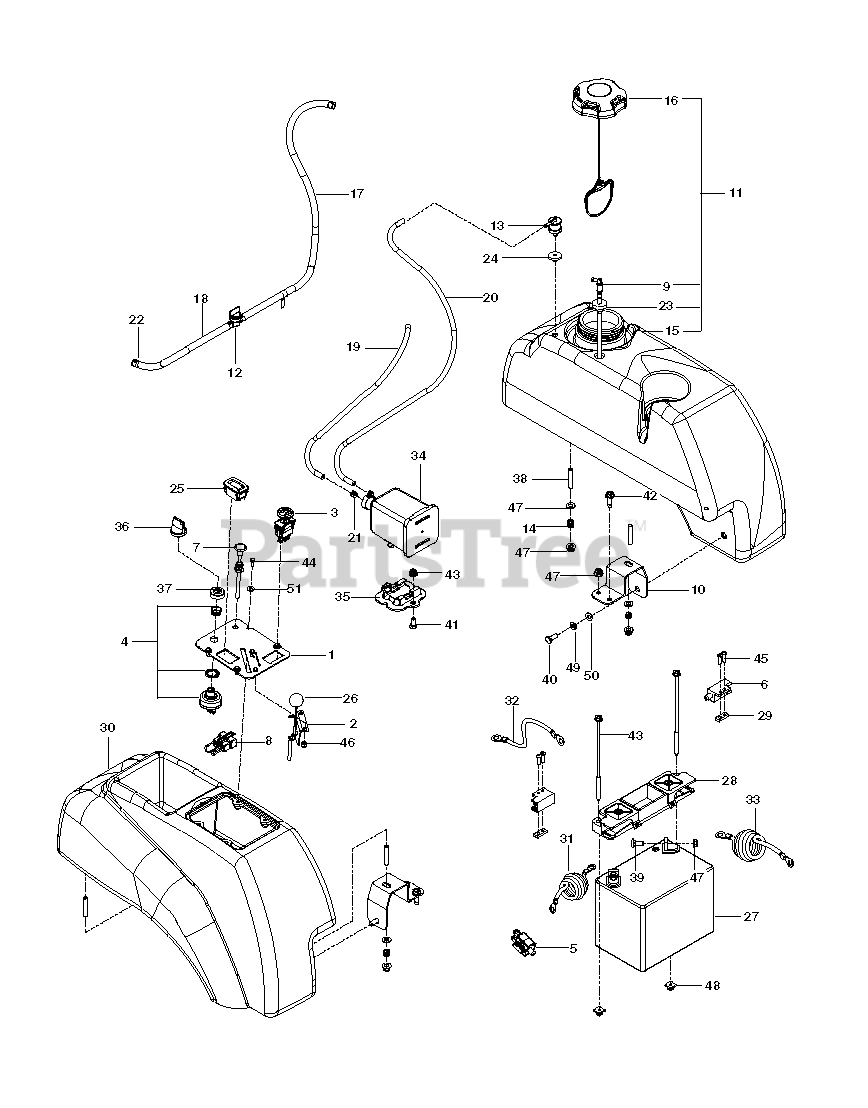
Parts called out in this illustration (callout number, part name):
1	PLATE.CONSOLE.BLACK
2	THROTTLE CABLE
3	SWITCH, PTO 10 AMP
4	SWITCH, IGNITION, INDAK
5	SWITCH, BRAKE 3P
6	SWITCH INTERLOCKT
7	CHOKE CABLE
8	PLUG, TIMER
9	FITTING, FUEL
10	SUPPORT, TANK, BLK
11	ASSEMBLY, LT TANK, EPA GRAY
12	FUEL VALVE
13	VALVE.FUEL.CHECK
15	TANK, FUEL, LT-EPA
16	CAP, FUEL
17	HOSE, FUEL .25 ID X 26"
18	GAS LINE 10"
19	HOSE, VAPOR 3/16 X 39"
20	HOSE.3/16"VAPOR.27"
21	CLAMP, HOSE
22	HOSE CLAMP
23	RUBBER GROMMET
24	GROMMET, CHECK VALVE
25	RP GUAGE.SRVCMNDR.HRMTR.
26	KNOB.ROUND.BALL.BLACK
27	BATTERY, 12 V 330 AMP
28	BATTERY HOLD DOWN
29	TAPPED PLATE
30	FENDER CONSOLE
31	POST.CABLE LONG
32	CABLE POSITIVE
33	NEG. CABLE, 28"
34	CANNISTER, CARBON
35	BRACKET, CANISTER
36	KEY, IGNITION
37	CAP IGNITION NUT
38	STUD, 5/16C
39	BOLT 5/16C X 3/4" CARRIAGE
40	HCS 5/16C X 3/4
41	HCS 5/16-18 X 5/8 GR 5 ZD
42	RP BLT 5/16-18 X 1 THRD FORM D
43	Bolt, 1/4-20 X 7.5
44	HCS #10-24 X 1/2
45	SCR #10-24 X .75 SKT HD BLK
46	NUT 10-24 NYLOC
47	5/16-18 NYLOC FLANGE NUT
48	PUSH NUT-NYLON
49	WASHER 5/16 LOCK
50	FLAT WASHER 5/16 SAE
51	WASHER #10
